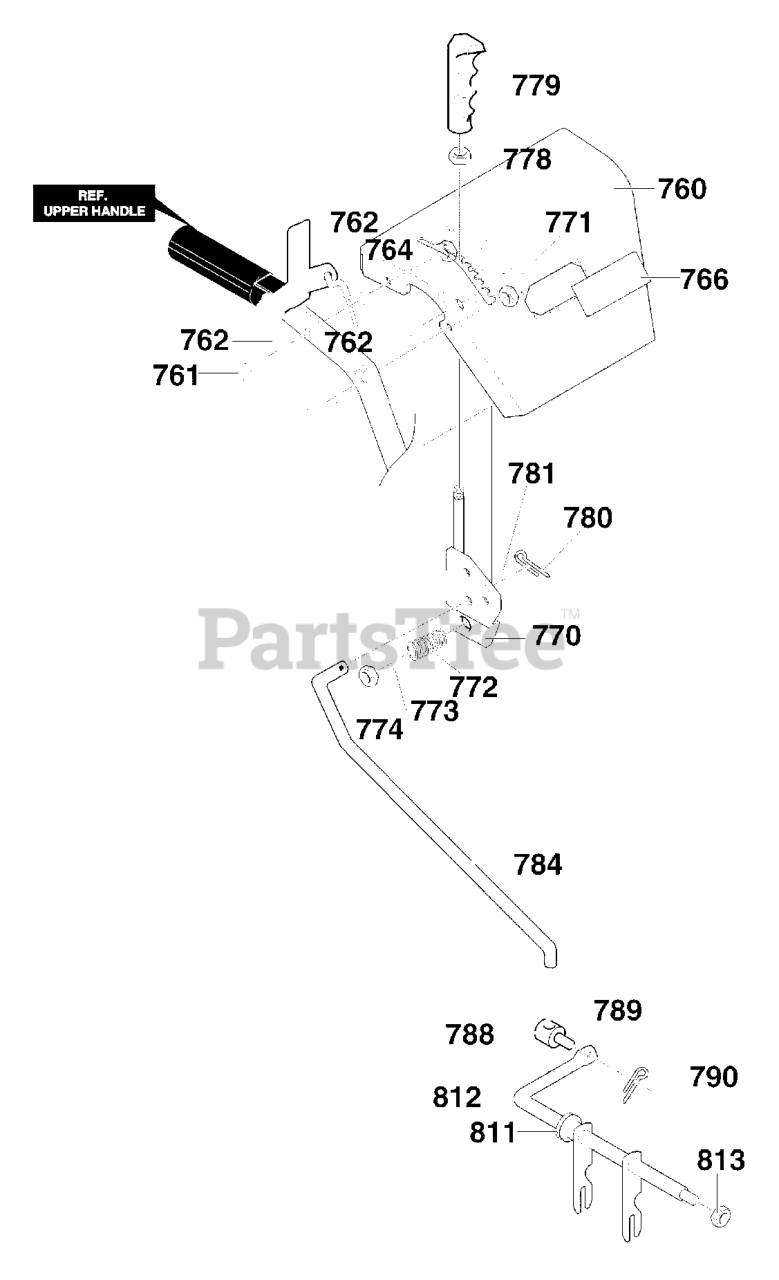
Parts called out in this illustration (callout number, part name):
760	ASSY. BAY LT
761	SCREW, 5/16-18 x 1.75
762	FLATWASHER
764	NUT, 5/16-18 HEXWDFLLK
766	PLATE, BLANKING LIGHT
770	HANDLE ASSY SPD CTRL
771	SCREW 3/8-16X2.00
772	SPRING
773	FLATWASHER
774	NUT, 3/8-16 HEXNYL
778	NUT, 3/8-16 REGHEX
779	HANDLE 3/8-16
780	PIN, COTTER
781	FLATWASHER
784	ROD, SPEED CONTROL
788	NUT, TRUNNION
789	FLATWASHER
790	COTTER PIN
811	BEARING, FLANGE
812	ROD, ASSY YOKE
813	NUT, 3/8-16 HXCTRLK
